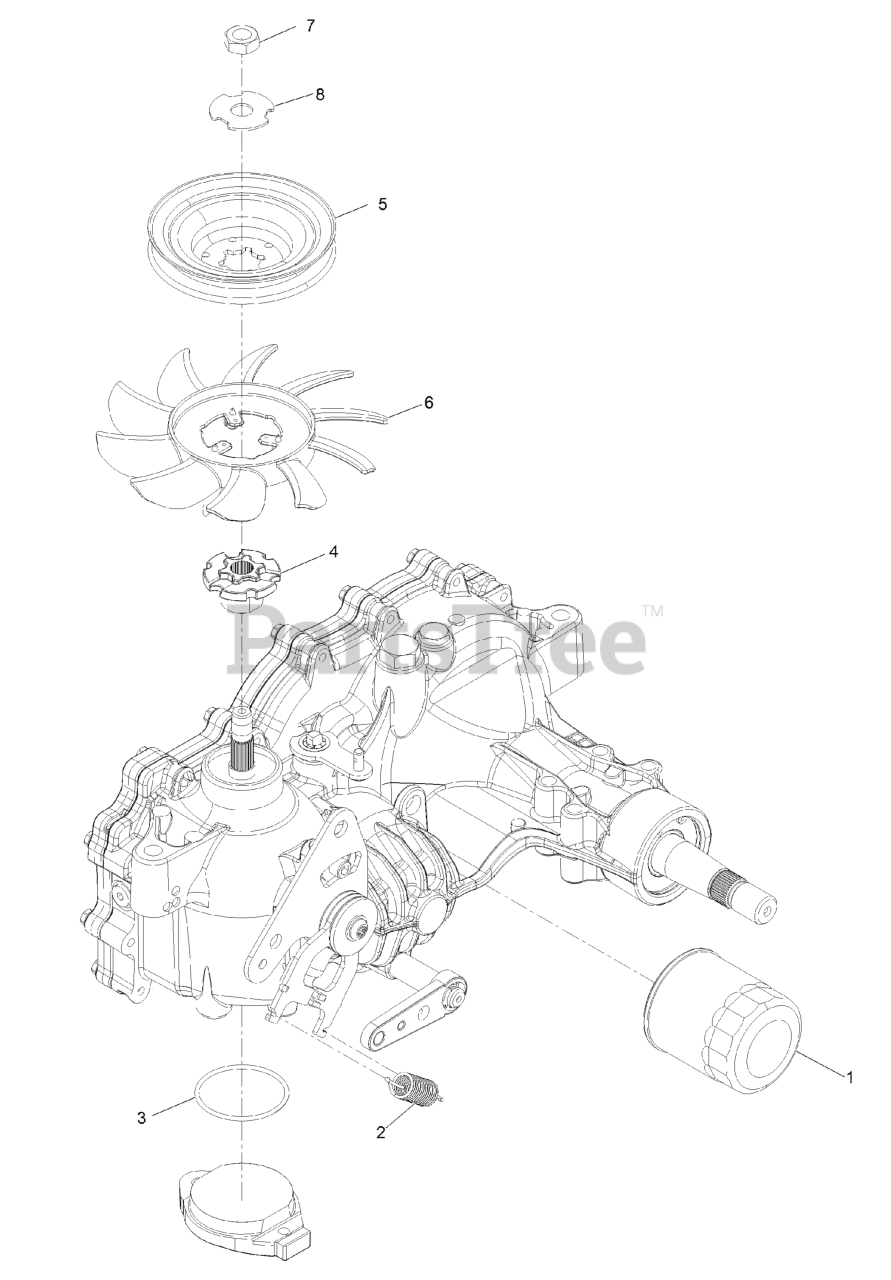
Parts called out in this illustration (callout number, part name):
1	ELEMENT-OIL FILTER, HYD
2	SPRING-EXTENSION
3	O RING-SEAL
4	HUB-PULLEY
8	WASHER-SLOTTED
99	BRAKE SHAFT SEAL KIT
